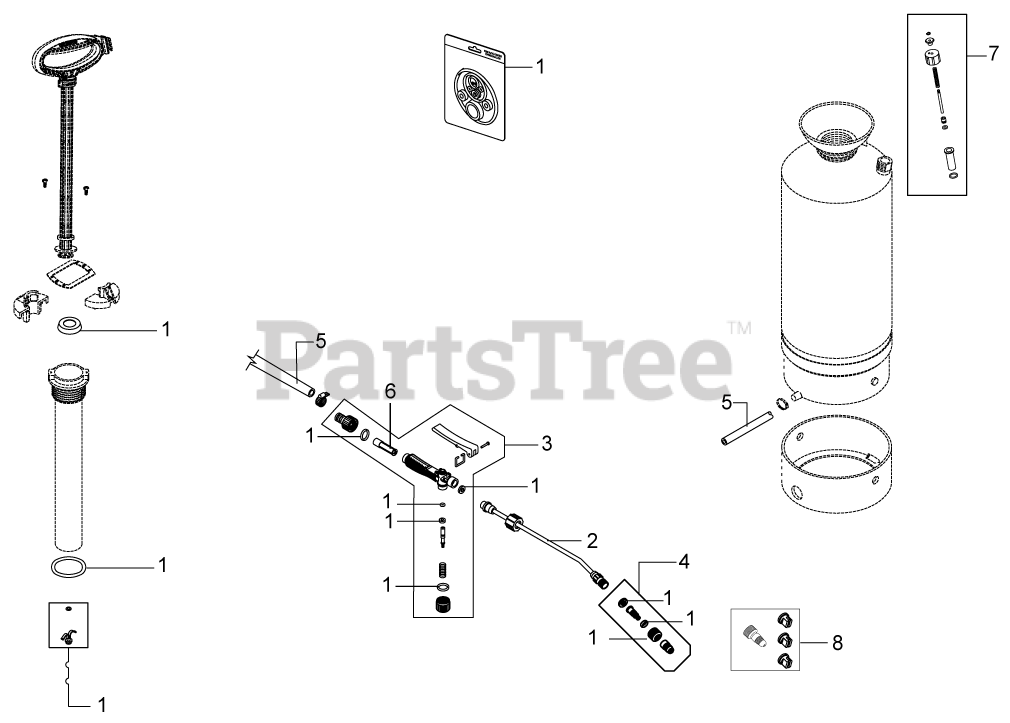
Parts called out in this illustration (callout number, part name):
1	KIT,SEAL REPAIR
2	WAND,SPRAY LANCE
3	RED SPRAY GUN
4	NOZZLE BODY ASS´Y
7	PRESSURE RELIEF VALVE
8	ADJUSTABLE NOZZLE AND 3 TIPS
